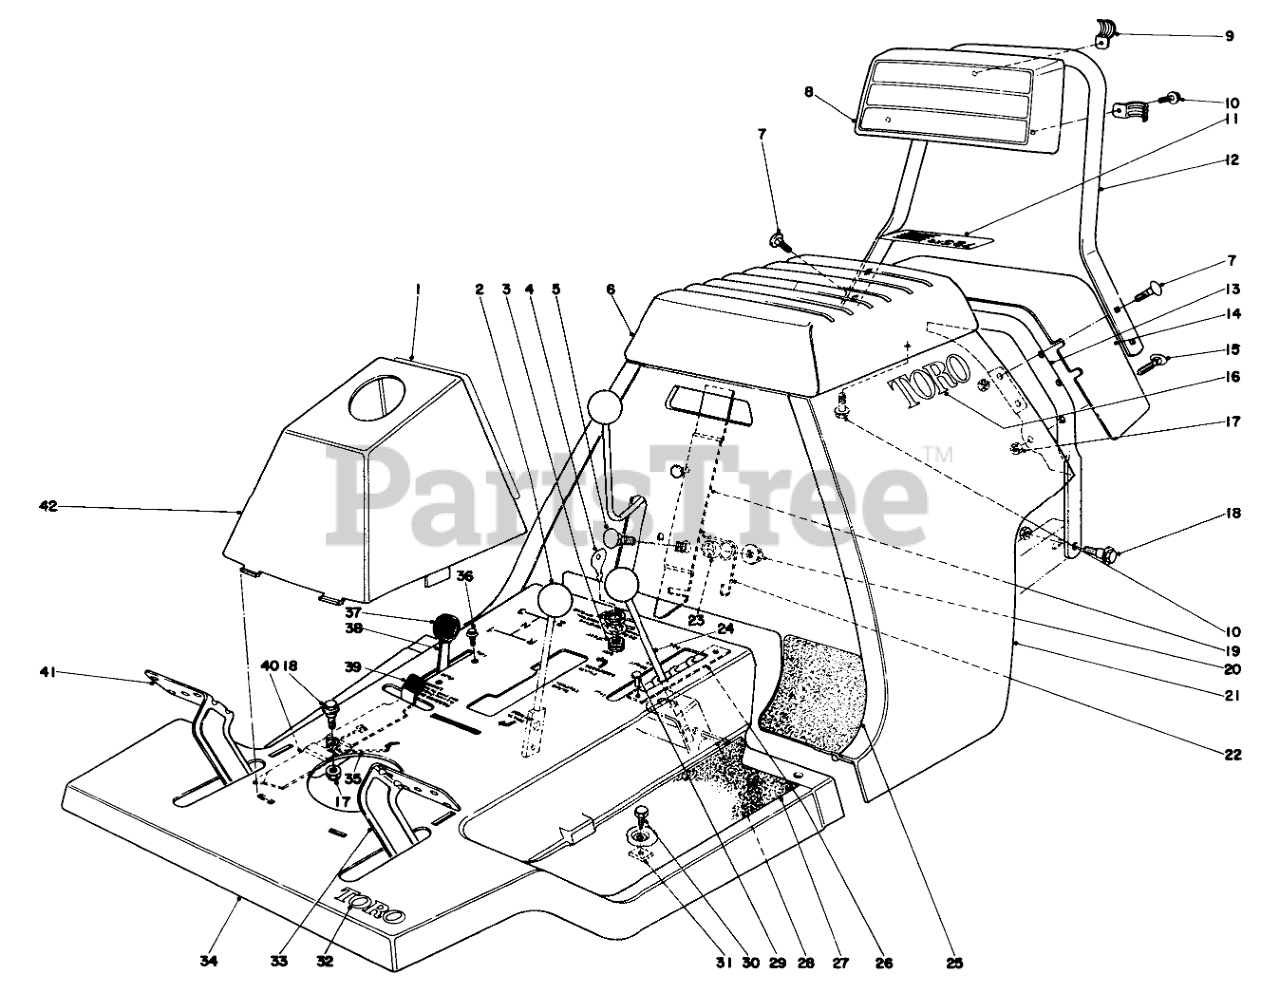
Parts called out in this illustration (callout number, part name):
1	Decal Tower
2	KNOB-CONTROL
3	STARTER SWITCH
4	Key
5	BOLT-CARR
7	SCREW-CARR
8	Backrest
9	CLAMP-CONDUIT
10	SCREW-HHF
11	Rear Extension Decal
12	Handle Upper
13	Handle Lower
14	Extension-Rear Body
15	HANDLE SCREW
16	Decal
17	NUT-LOCK, CONE
18	SCREW-SHOULDER
19	Handle Latch
20	NUT-HF
21	Rear Body
22	Latch Return Spring
23	Spacer
24	Height of Cut Lever
25	Heel Pad L.H.
26	Height Adjustment Plate
27	Foot Tread L.H.
28	PIN-SPRING
30	SCREW-HH
31	NUT-TINNERMAN
32	DECAL
33	Clutch Pedal
34	Front Body
35	SPRING-PARKING BRAKE
36	8X1/2 SELF TAP SCREW
38	THROTTLE CONTROL ASM
39	TIP-PARKING BRAKE
40	Parking Brake
41	Brake Pedal
42	Tower
